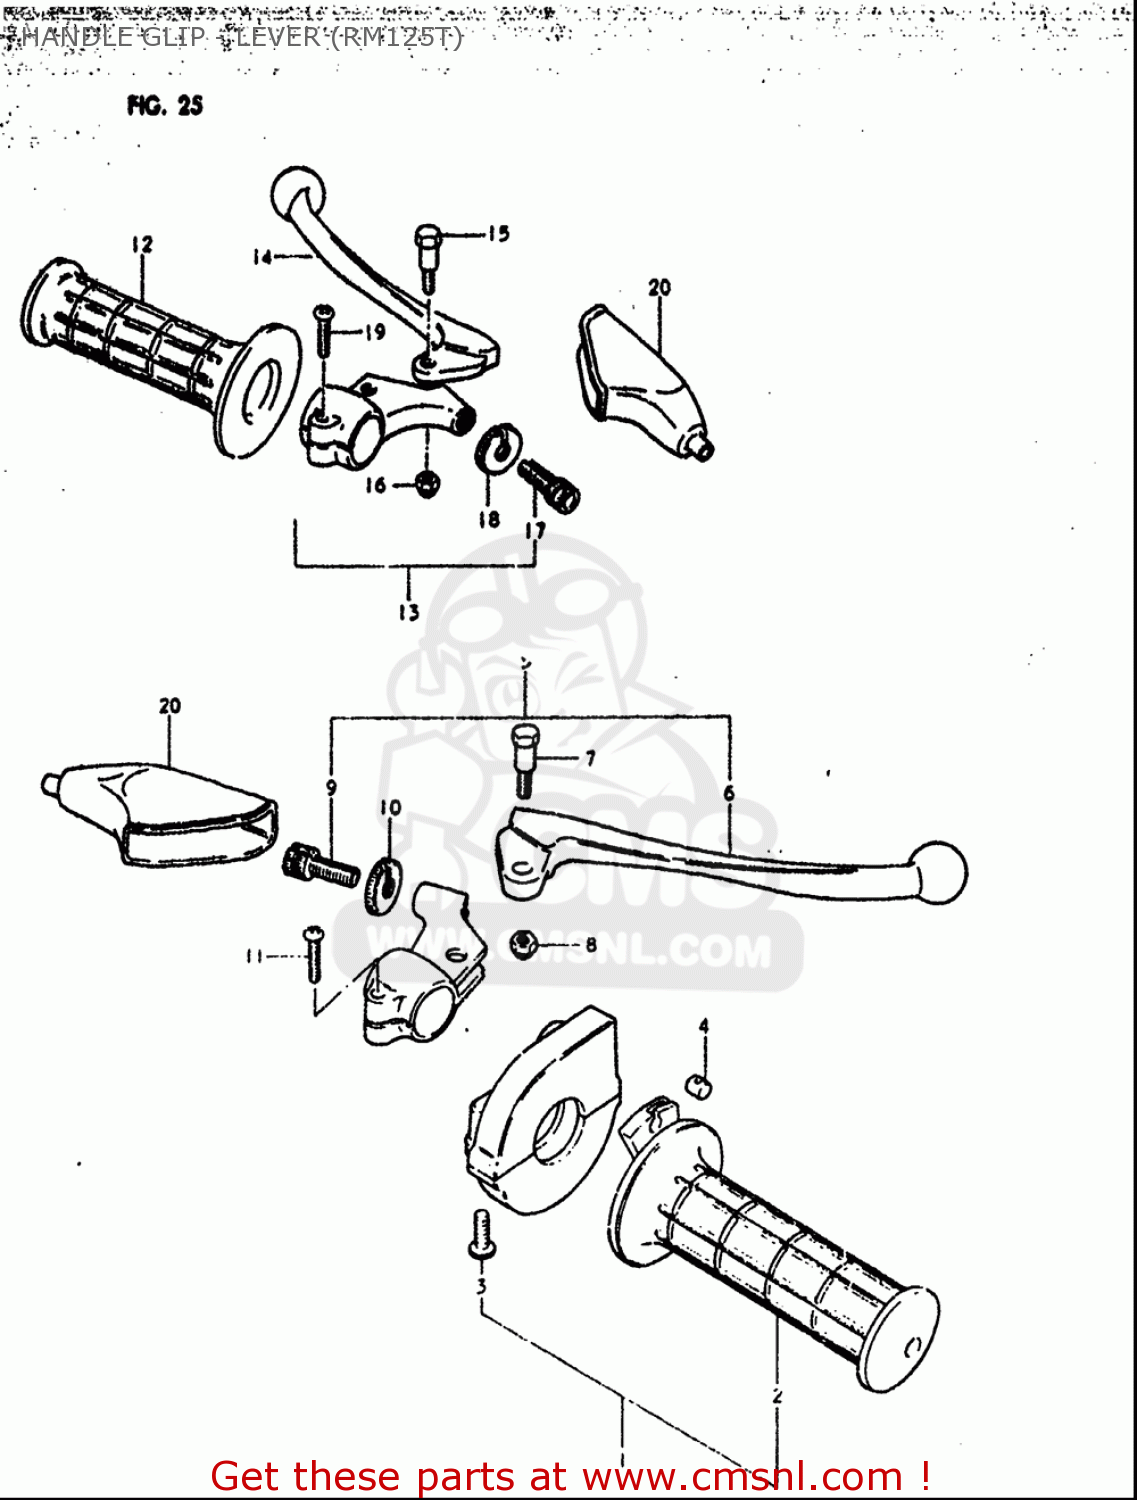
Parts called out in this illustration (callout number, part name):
1	CASE,THROTTLE
2	GRIP,THROTTLE
3	SCREW
4	PIECE,THROTTLE END
5	LEVER ASSY,BRAKE
6	LEVER,BRAKE
7	BOLT,LEVER PIVOT
8	NUT 6MM
9	ADJUSTER,CABLE
10	NUT,CABLE ADJUSTER
11	SCREW
12	GRIP,L
13	LEVER ASSY,CLUTCH
14	LEVER,CLUTCH
15	BOLT,LEVER PIVOT
16	NUT 6MM
17	ADJUSTER,CABLE
18	NUT,CABLE ADJUSTER
19	SCREW
20	COVER,CLUTCH LEVER
